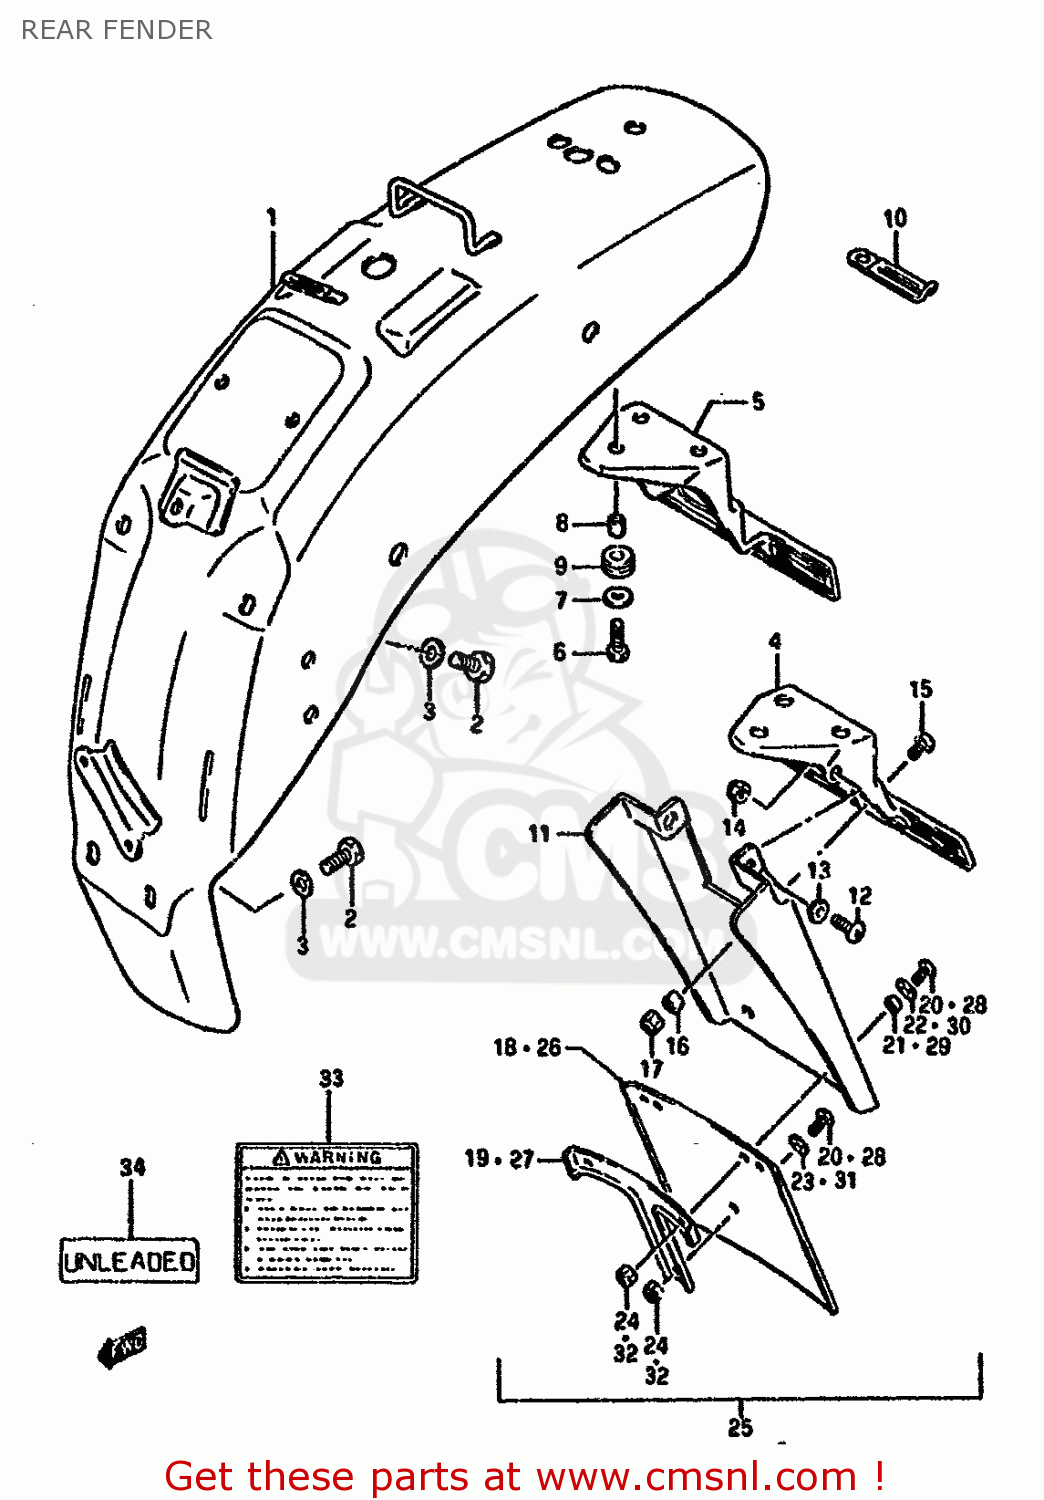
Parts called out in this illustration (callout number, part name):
1	FENDER,REAR
2	BOLT 8X25
3	WASHER 8MM
4	BRACKET,LICENSE PLATE
5	BRACKET,LICENSE PLATE
6	BOLT
7	WASHER
8	SPACER (6.1X9X9)
9	CUSHION
10	CLAMP
11	EXTENSION,REAR
12	SCREW
13	WASHER
14	NUT
15	SCREW
16	SPACER(6.2X8.3X6.1)
17	NUT
18	MUD FLAP, REAR FENDER
19	PLATE, MUD FLAP
20	SCREW, FRONT & REAR
21	SPACER (5.5X8X4)
22	WASHER,5MM
23	WASHER
24	NUT 8MM
25	MUDFLAP SET,REAR
26	MUD FLAP, REAR FENDER
27	PLATE, MUD FLAP
28	SCREW, FRONT & REAR
29	SPACER (5.5X8X4)
30	WASHER,5MM
31	WASHER
32	NUT 8MM
33	LABEL, WARNING SAFETY
34	LABEL,CAUTION
35	LABEL,TIRE AIR PRESSURE
36	MANUAL,OWNER'S
